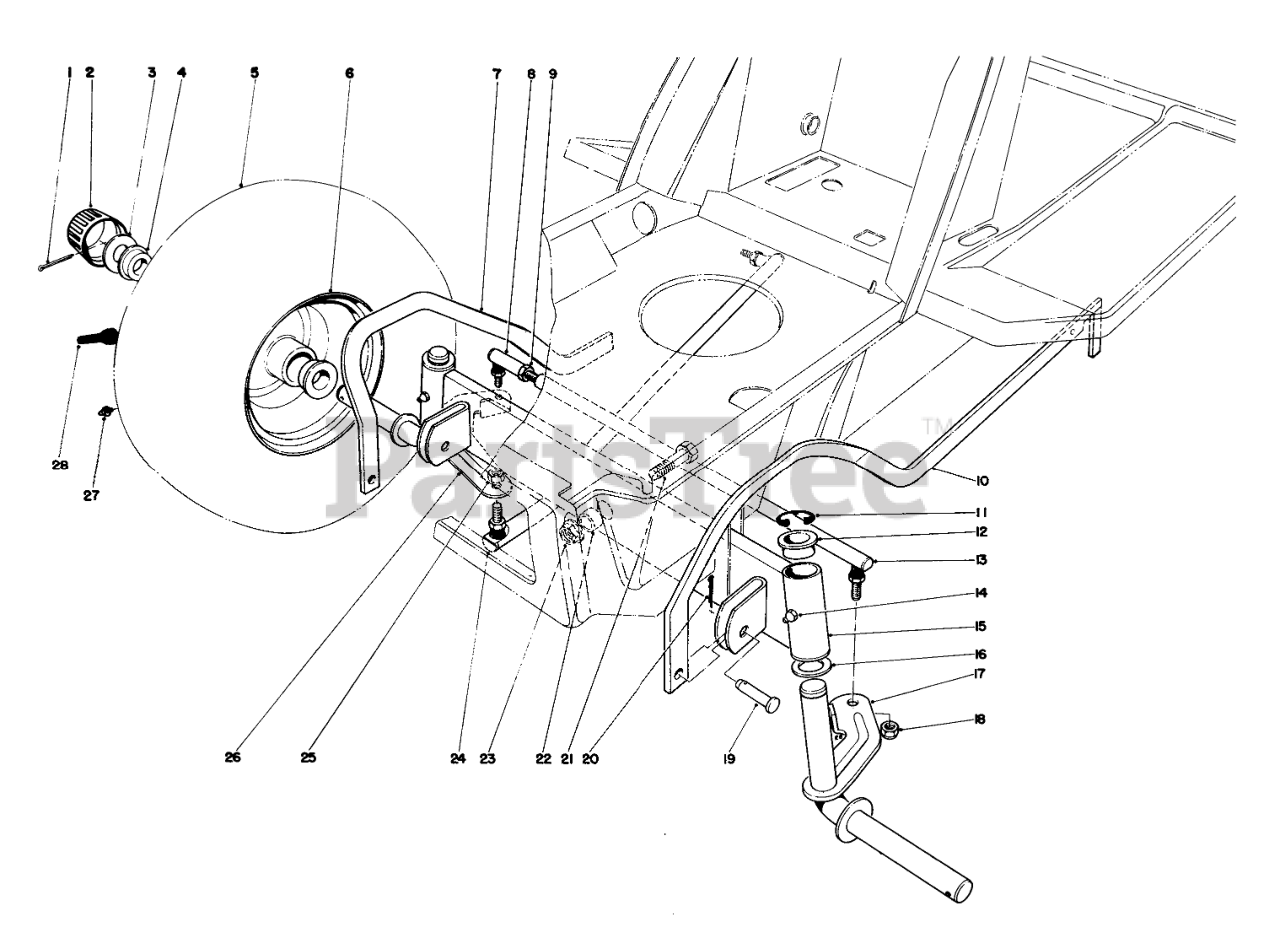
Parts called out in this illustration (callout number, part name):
1	PIN-COTTER
2	Cap-Hub
3	WASHER-PLAIN
4	Bearing
5	FRONT TIRE
6	FRONT RIM
7	R/F SCISSORS LINK WAB
8	JOINT-BALL
9	NUT-JAM
10	LF SCISSORS LINK WAB
11	E-RING
12	BEARING-FLANGE
13	Tie Rod Steering (Incl. Ref. #8 & 9)
14	GREASE FITTING
15	Front Axle (Incl. Ref. #12)
16	WASHER-THRUST
17	LH SPINDLE WA PP
18	NUT-LOCK, NI
19	PIN-CLEVIS
20	PIN-COTTER
21	SCREW-HH
22	SPACER-AXLE, FRONT
23	NUT-HF
24	STEERING ARM B
25	NUT-HEX
26	RH SPINDLE WA PP
27	FITTING-GREASE
28	STEM-VALVE
